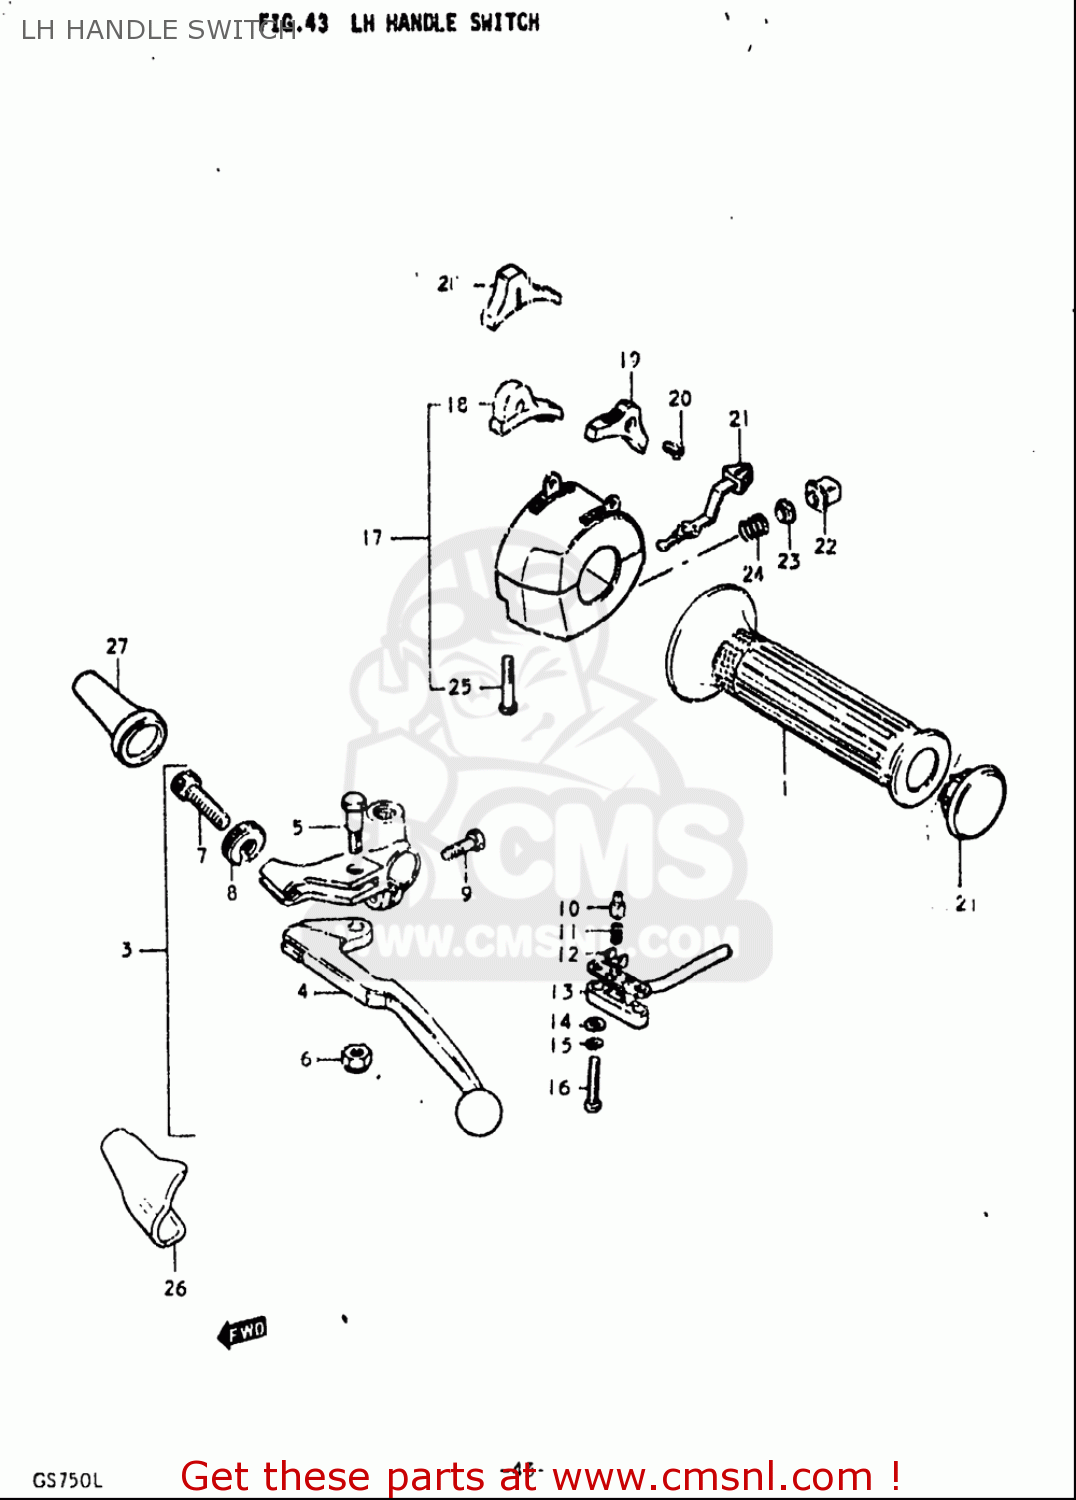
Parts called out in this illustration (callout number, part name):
1	GRIP,L
2	CAP,GRIP END
3	LEVER ASSY,CLUTCH
4	LEVER,CLUTCH
5	BOLT,LEVER PIVOT
6	NUT 6MM
7	ADJUSTER,CABLE
8	NUT,CABLE ADJUSTER
9	BOLT
10	CONTACT,SWITCH
11	CONTACT,SWITCH
12	CONTACT,SWITCH
13	COVER,FR BK TERMINAL BASE
14	WASHER
15	WASHER,LOCK
16	SCREW
17	SWITCH ASSY,HANDLE,L
19	KNOB,DIMMER SWITCH
20	SCREW
21	KNOB,TURNSIGNAL
22	BUTTON,HORN
23	CONTACT
24	SPRING
25	SCREW
26	COVER,CLUTCH LEVER
27	BOOT,CLUTCH CABLE
28	KNOB,LIGHTING SWITCH
